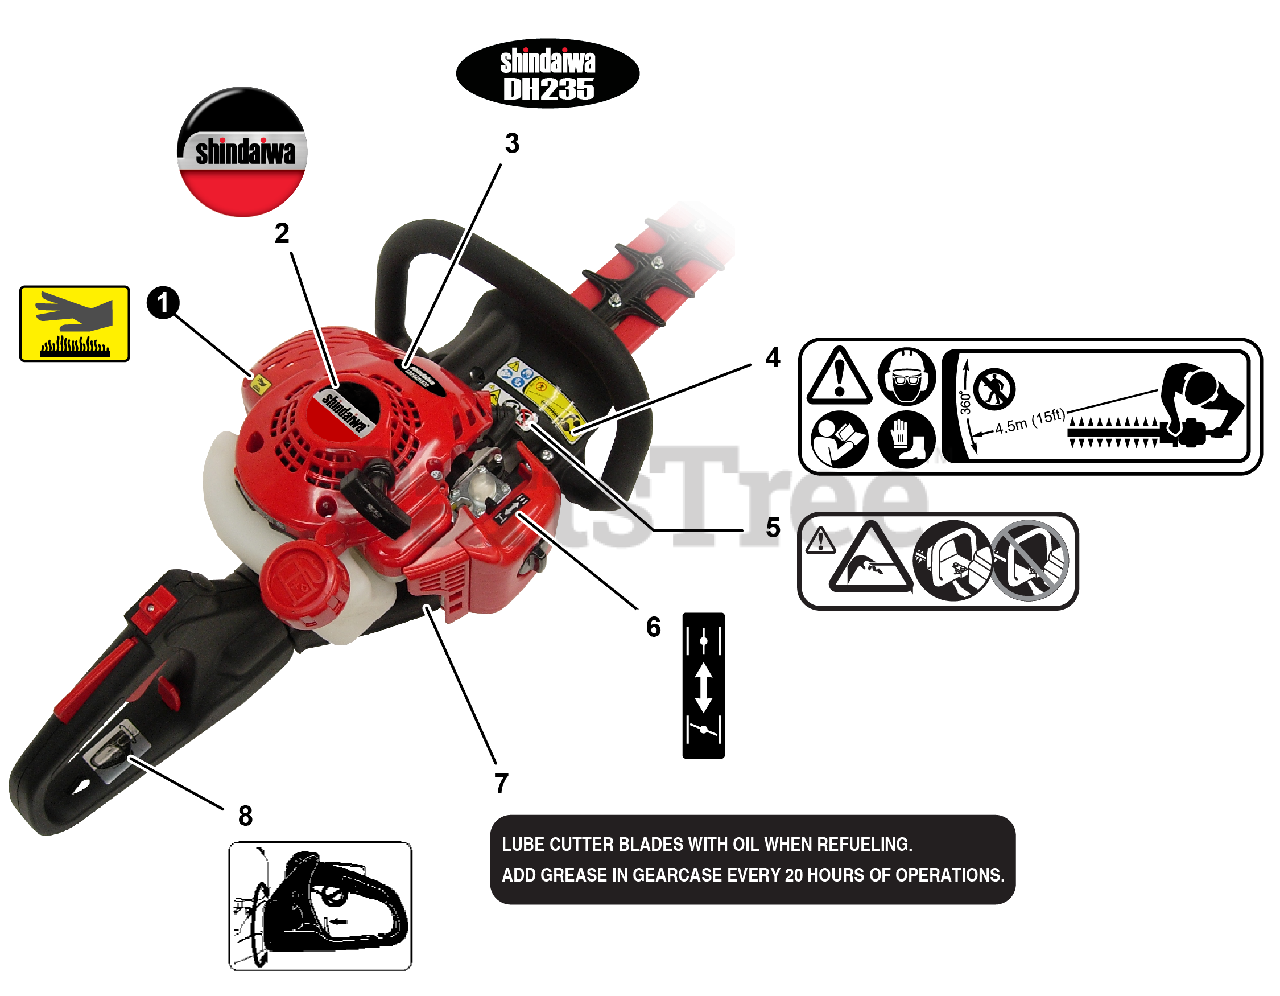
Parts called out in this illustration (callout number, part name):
1	LABEL, CAUTION - HOT
2	LABEL, shindaiwa
3	LABEL - MODEL DH235
4	LABEL, CAUTION - ISO
5	LABEL, CAUTION
6	LABEL, CHOKE
7	LABEL, LUBE BLADES
8	LABEL, CAUTION
